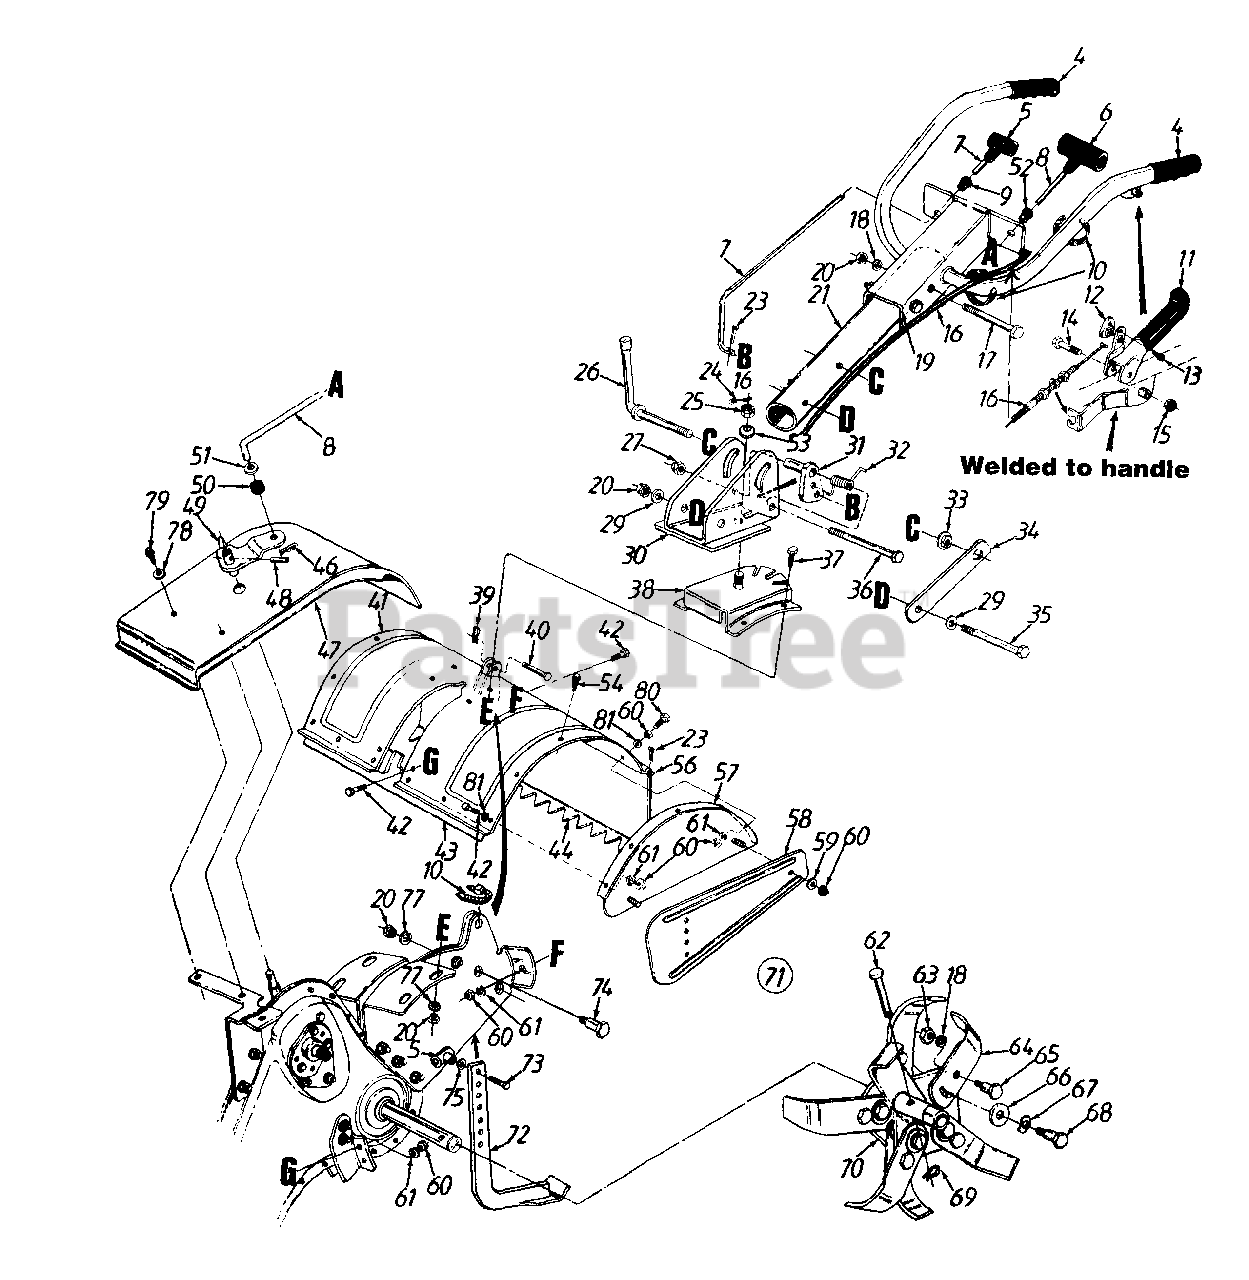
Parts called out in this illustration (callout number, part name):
4	Handle Grip
5	Small "T" Knob
6	Large "T" Knob
7	Clutch Rod
8	Control Rod 37" Lg.
9	Snap On Bushing 3/8" Dia.
10	Cable Tie-Self Clinching
11	Clutch Grip Ass'y. - L.H.
12	Barrel Cable Hold Down
13	Hex B-Tap Scr. #10 x .44" Lg.
14	Hex Bolt 3/8-24 x 2.25" Lg.
15	Hex Jam L-Nut 3/8-24 Thd.
16	Clutch Control Cable 46" Lg.
17	Hex Bolt 3/8-16 x 3.00" Lg.
18	L-Wash. 3/8" I.D. - H.D.
24	Cotter Pin 3/32" Dia. x 1.25" Lg.
25	Hex Slotted Nut 5/8-18 Thd.
26	Handle Adj. Crank
27	Hex Cent. L-Nut 3/8-16 Thd.
29	Bell-Wash. .4" I.D. x .87" O.D.
30	Handle Pivot Bracket
31	Positioner Crank Ass'y.
32	Spring Handle Adj. (Torsion)
33	Hex Flange Nut 3/8-24 Thd.
34	Bracket Hex Nut Retainer
35	Hex Bolt 3/8-16 x 3.25" Lg."
36	Hex Bolt 3/8-16 x 3.00" Lg. - Gr. 8
37	Hex Bolt 3/8-16 x 1" Lg.
40	Clevis Pin .375" Dia.
43	Bracket Reinforcement - 18"
46	Intern. Cotter Pin 5/16" Dia.
49	Shifting Crank Ass'y.
50	Rubber Washer .33" I.D.
51	Fl-Wash. .4" I.D. x 1.25" O.D.
52	Snap On Bushing 1/2" Dia.
53	Bell-Wash..63" I.D. x 1.25"
54	Hex Wash. Tap Scr.
56	Tiller Flap Rod
57	End Cover Ass'y.
60	Hex Nut 5/16-18 Thd.
61	L-Wash. 5/16" I.D.
62	Clevis Pin .375" Dia.
63	Hex Nut 3/8-24 Thd.
64	13" Dia. Articulating Tine
65	Shld. Bolt 1/2" Dia. x .175
66	Fl-Wash. .51" I.D. x 1.50"
67	Bell-Wash. .515" I.D. x 1.14"
68	Shld. Bolt 1/2" Dia. x .320
69	Intern. Cotter Pin
70	Tine Adapter Ass'y. 18"
71	Tine Ass'y. Comp. 18"
72	Depth Bar
73	Hex Bolt 3/8-16 x .75" Lg.
74	Shld. Bolt 1/2" I.D. x .62" Lg.
75	Fl-Wash. 3/8" I.D. x 5/8" O.D.
77	L-Wash. 3/8" I.D.
78	Fl-Wash. .281" I.D. x .62"
79	Hex Wash. Self-Tap Scr. 1/4-20 x .50" Lg.
80	Hex Bolt 5/16-18 x 1 1/4" Lg.
81	Cap L-Nut 5/16-18 Thd.
